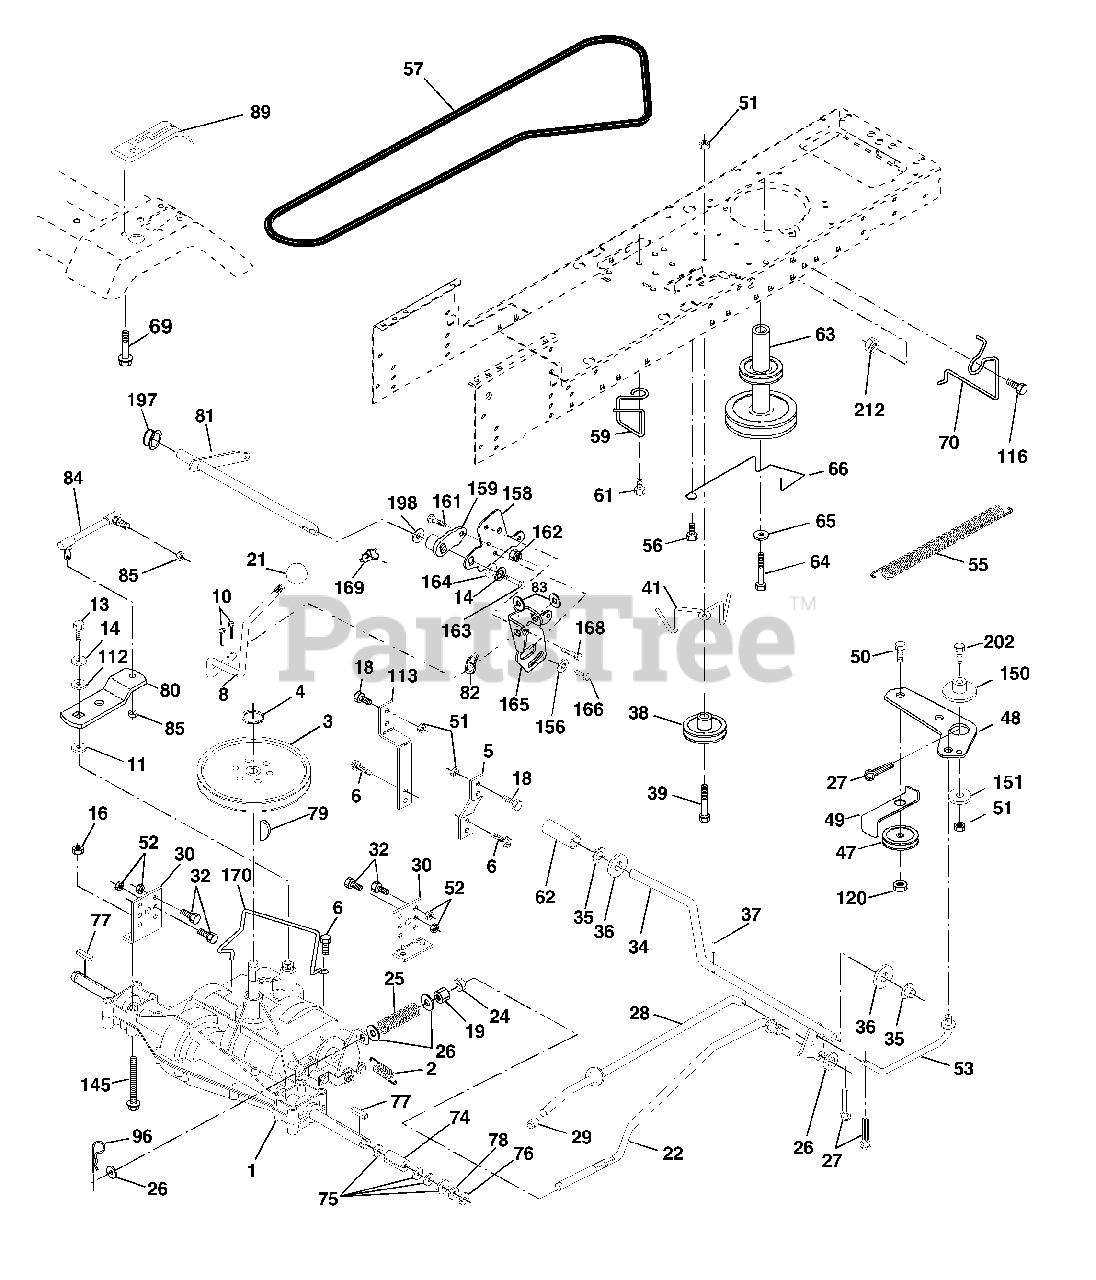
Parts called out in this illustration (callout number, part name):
2	Spring Return Brake T/a Zinc
3	Pulley Transaxle 18/20" tires
4	Ring Retainer # 5100-62
5	Strap Torque 30 Degrees
6	Screw 5/16-18 x 3/4
8	Rod Shifter Fender STLT
10	Pin Cotter 1/8 x 1 Cad
11	Washer Plate Shf 388 Sq Hole
13	Bolt 1/4-28unf Gr8 W/Patch
14	Washer Lock Hvy Helical 1/4
16	Nut Lock Hex w/Ins. 5/16-18 Unc
18	Bolt Fin Hex 3/8-16 Unc x 1 Gr 5
19	Nut Lock Hex w/Ins. 38/-16 Unc
21	Knob Deluxe
22	Rod Brake Blk Zinc 26 840
24	Nut Hex Jam 3/8-16 Unc
25	Spring Rod Brake 2 00 Zinc
26	Washer 13/32 x 13/16 x 16 Ga.
27	Pin Cotter 1/8 x 3/4 Cad
28	Rod Brake Parking Lt/Yt
29	Cap Brake Parking
30	Bracket Mtg Transaxle
32	Bolt Hex Hd 5/16-18 Unc x 3/4
34	Shaft Asm Pedal Foot
35	Bearing Nylon Blk 629 Id
36	Washer 21/32 x 1 x 16 Ga
37	Pin Roll 3/16 x 1"
38	Pulley Composite Flat
39	Bolt Fin Hex 3/8-16unc x 3
41	Keeper Belt Idler
47	Pulley Idler
48	Bellcrank Clutch Grnd Drv STL
49	Retainer Belt Style Spring
50	Bolt Hex Hd 3/8-16 Unc x 1-1/2
51	Nut Crownlock 3/8-16 UNC
52	Nut Crown Lock 5/16-18
53	Link Clutch 7 66
55	Spring Return Clutch 6 75
56	Screw 3/8-16 x 1-1/4
57	V-Belt Gd Drive
59	Keeper Belt Centerspan
61	Screw 3/8-16 x .875
62	Cover Pedal Blk Round
63	Pulley Eng
64	Bolt Hex 7/16-20 x 4 Gr 5
65	Washer Lock Hvy Hlcl Spr 7/16
66	Keeper Belt Engine
69	Screw Hex Wsh Hi-Lo 1/4-1/2 Unc
70	Guide Belt Mower Drive RH
74	Spacer Split
75	Washer 25/32 x 1 1/4 x 16 Ga
76	E-ring #5133-75
77	Key Square
78	Washer 25/32 x 1-5/8 x 16ga
79	Key Woodruff
80	Arm, Shift
81	Shaft Assembly
82	Spring, Torsion
83	Washer 17/32 x 3/4 x 16 Gauge
84	Link Transaxle
85	Nut, Nylock
89	Console, Shift, STLT
96	Retainer Spring
112	Washer 9/32 x 3/4 x 10 Ga
113	Strap Torque
116	Bolt Rd Hd Sqnk 3/8-16 x 1 Unc
120	Nut Lock Flg. 3/8-16 Unc
145	Bolt Hex Flghd 5/16-18 x Gr.5
150	Spacer Retainer
151	Washer 13/32 x 2 x 10 Ga.
156	Washer Srrted 5/16ID x 1 .125
158	Bracket Shift Mount
159	Hub Tapered Flange Shift Lt
161	Bolt Rdhd Sqnk 1/4-20 x 3/4 Gr.5
162	Nut Crownlock 1/4-20 UNC
163	Bolt Hex Fin 1/4-20 UNC x 1 Gr.5
164	Washer 5/8 x .281 x 10 Ga.
165	Bracket Pivot Lever
166	Screw 5/16-18 x 5/8
168	Bolt shoulder 5/16-18 x .561
169	Plate Fastening Lt
170	Keeper Belt T/A
197	Nyliner Snap-In 5/8" ID
198	Washer Nyl 7/8ID x .105"
202	Bolt Carr Sh 3/8-16 x 1-1/2 Gr.5
212	Nut Hex Flange Lock
